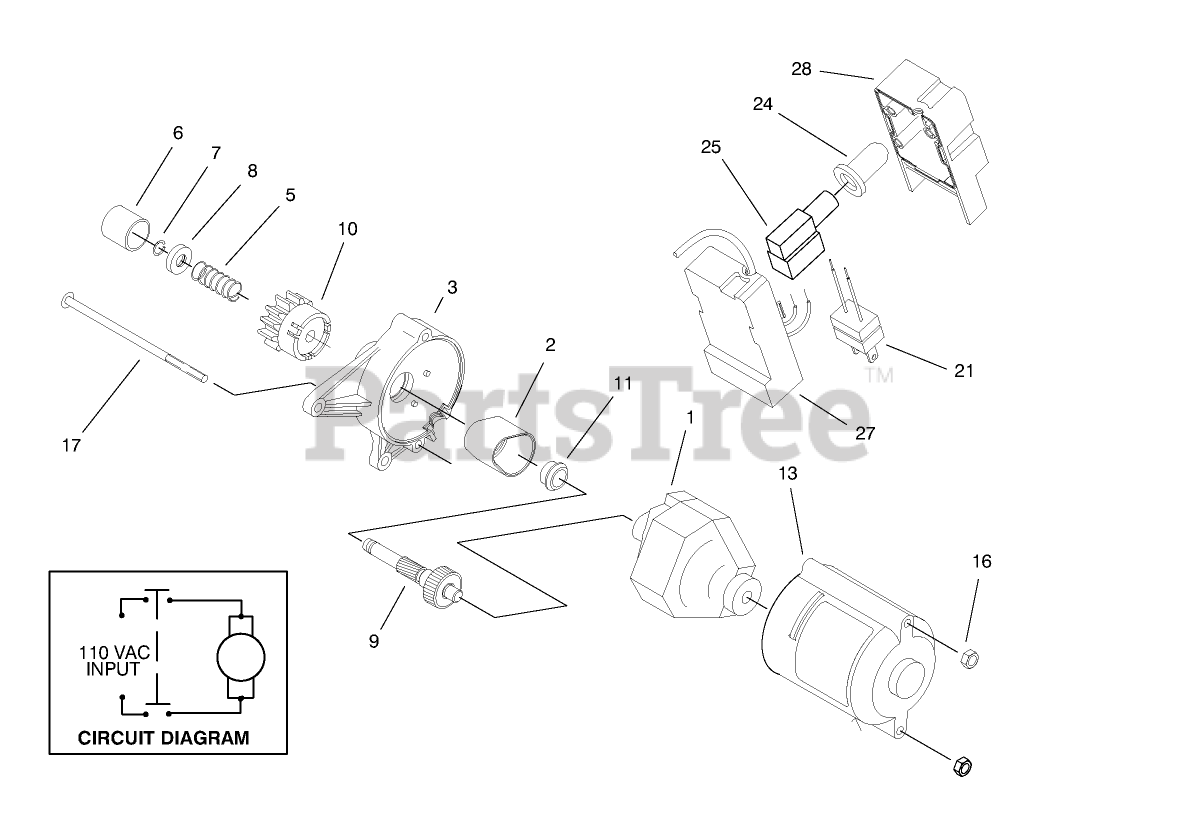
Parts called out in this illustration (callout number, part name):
1	STARTER MOTOR ASM
2	COVER-GEAR
3	Housing-Starter
5	SPRING
6	CAP-PINION
7	RING-LOCK
8	PINION STOP
9	Asm-shaft & Gear
10	PINION ASM
11	BUSHING
13	HOUSING COVER
16	NUT-LOCK, NI
21	PLUG-POWER
24	BOOT-SWITCH
25	SWITCH-STARTER
27	OBS BASE X
28	Cap-Switch Housing
